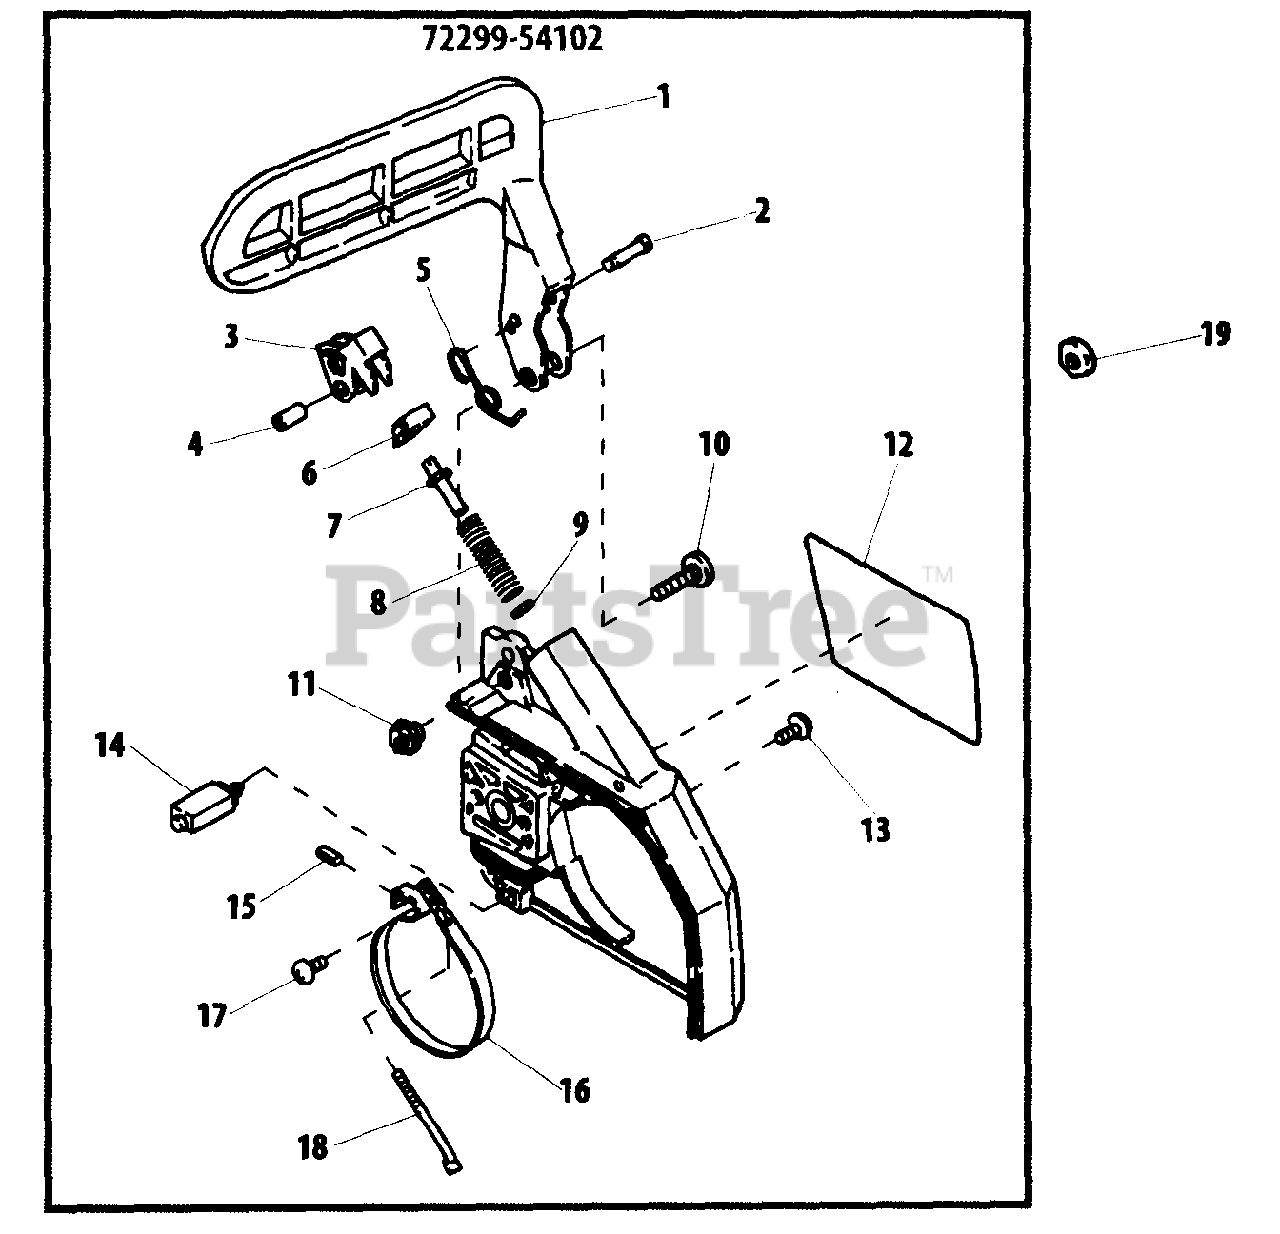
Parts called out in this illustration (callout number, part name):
1	LEVER
2	PIN - STOPPER
3	LEVER - INNER
4	PIN, METERING LEVER
5	SPRING, RELIEF
7	SCREW, ADJUST
8	SPRING, BRAKE
9	WASHER - 6
10	BOLT, LEVER
11	NUT
12	LABEL - MODEL
13	SCREW - 3X8
14	CATCHER, CHAIN
15	PIN
16	BAND, BRAKE
17	SCREW - 5X10
18	ROD, ADJUST
19	NUT - 8
72299-54102	BRAKE LEVER ASSY
